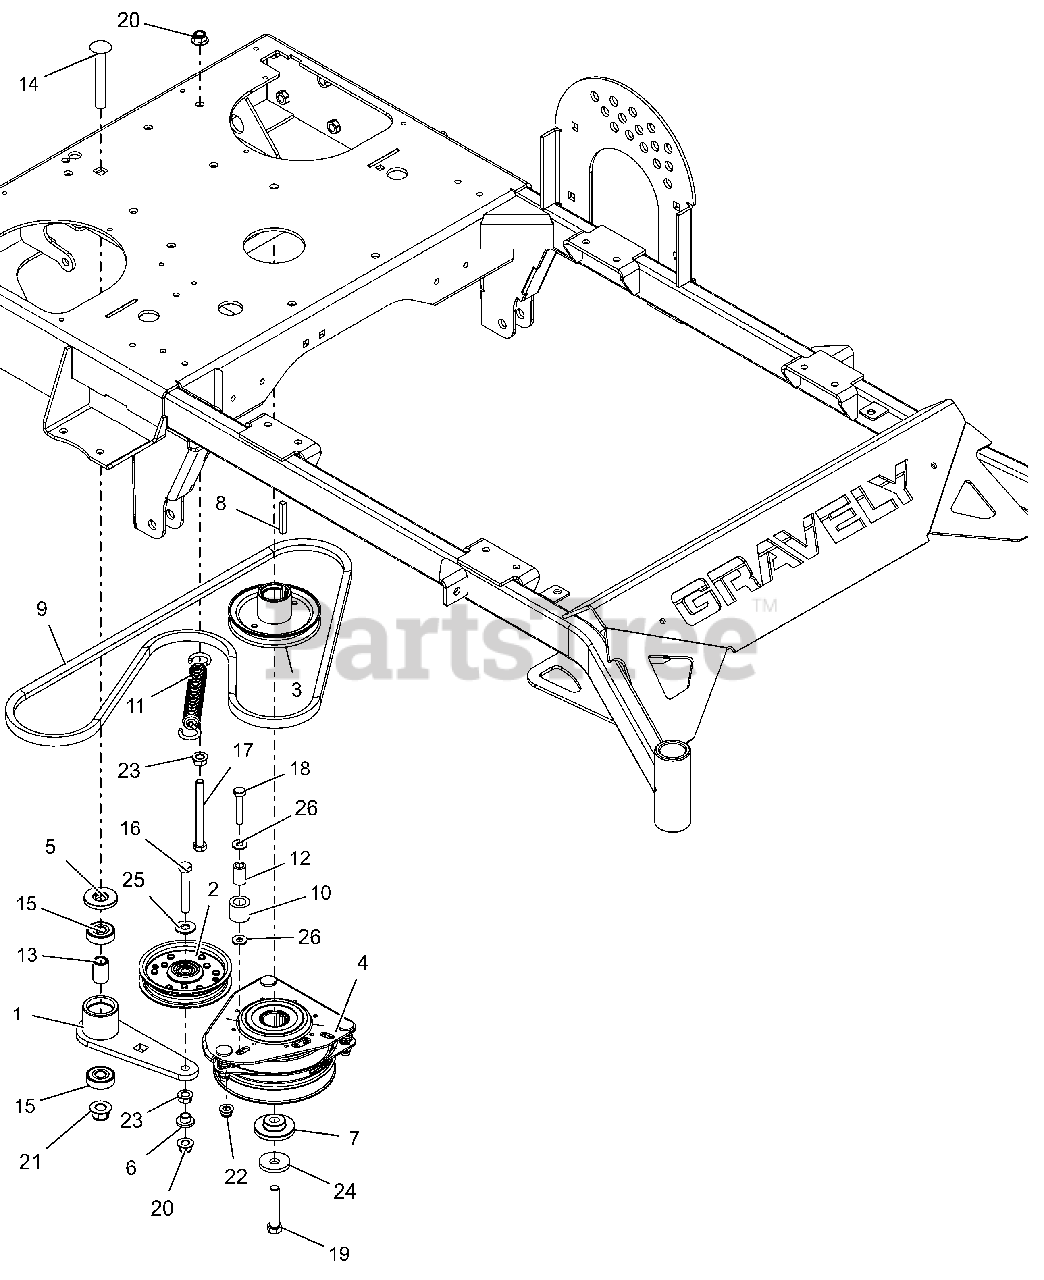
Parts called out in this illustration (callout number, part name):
1	WLDMT, PRO WALK IDLER ARM (BLACK)
2	ASM, 4" IDLER (.75 WIDE)
3	SHEAVE, ENGINE 4.50 x 1.004 ID (BLACK)
4	CLUTCH, OGURA GT1A-AR03
5	SPACER, IDLER ARM
6	BSHG-FLG .385X.500X.875X.406
7	BSHG-FLG .469X1.06X.574X2.0
8	KEY-STR .25X1.75X.25
9	BELT,HA WRAPPED
10	BUMPER,RUBBER .62X1.0X.88 LG
11	SPRING, EXTENSION
12	BUSH.,S.391X.622X.950 ST
13	SPACER .510 X .75 X 1.1485
14	@BLT-RHDSSQNK .50-13X3.50 G5YZ
15	BRG-BALL .500X1.38X.437
16	@BLT-HEX .38-16X2.50 GR5 YWZC
17	@BLT-HEX .38-16X3.75 GR5 YWZC
18	@BLT-HEX .31-18X1.75 GR5 YWZC
19	BLT-HEX .44-20X2.25 G8YZNYTORQ
20	@NUT-LK-NYL-FLG .38-16 YWZC
21	@NUT-LK-NYL-FLG .50-13 YWZC
22	@NUT-LK-NYL-FLG .31-18 YWZC
23	@NUT-SPNLK-FLG .375-16 YWZC
24	WASHER, 7/16" SPRING DISK
25	@WSHR-FL-STL.438X1.00X.083 YWZ
26	@WSHR-FL-STL.312X.734X.065 YWZ
